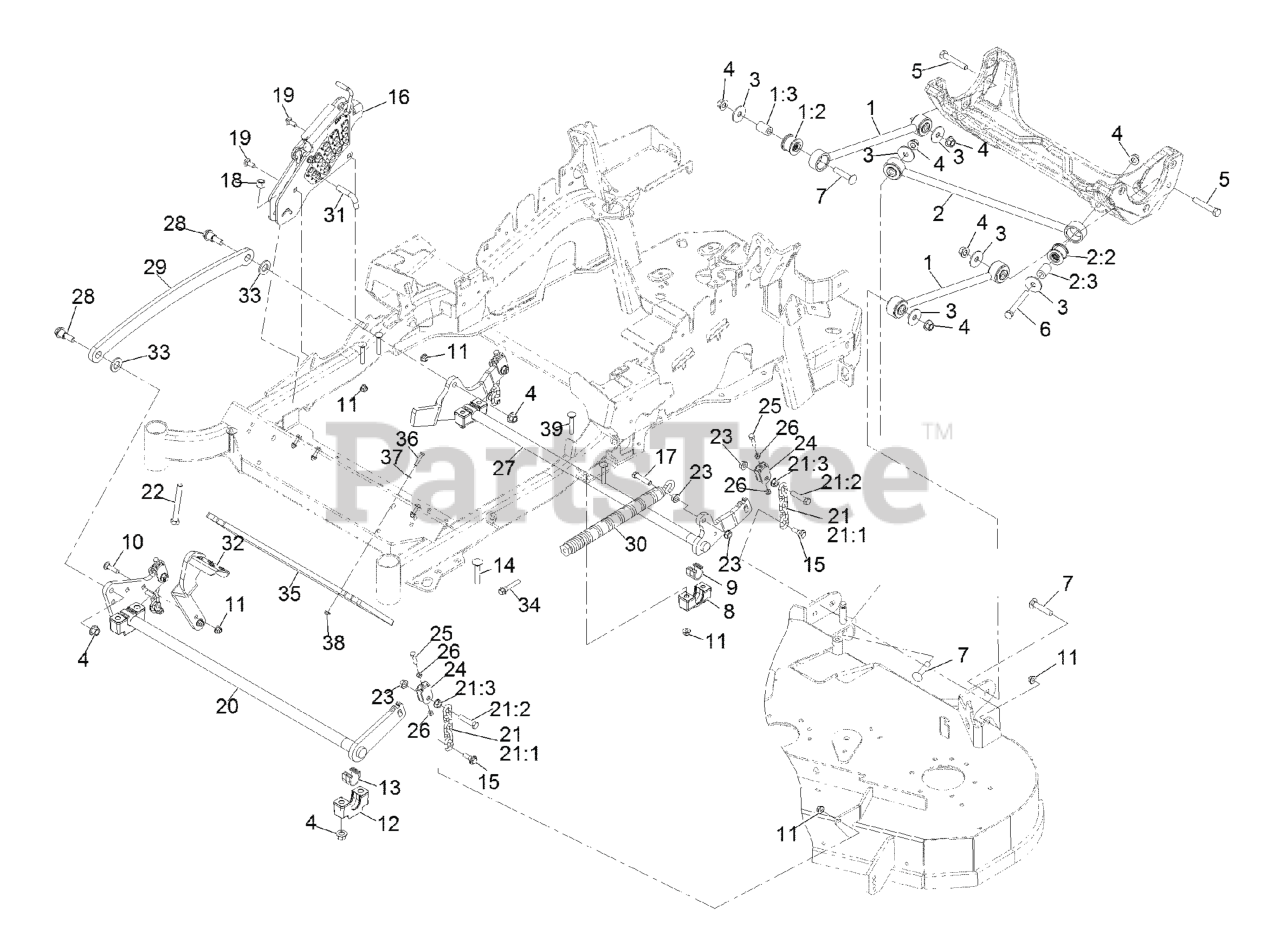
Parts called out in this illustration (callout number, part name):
1	DECK STRUT ASM
1:2	BUSHING-SUSPENSION, RUBBER
2	PANHARD ROD ASM
2:2	BUSHING-SUSPENSION, RUBBER
3	WASHER-THRUST
4	Nut-Lock 1/2-13
5	SCREW-HH
6	SCREW-HH
7	SCREW-CARR
8	SUPPORT-CROSS SHAFT, BEARING REAR
9	BEARING-CROSS SHAFT, REAR
10	SCREW-CARR
11	NUT-HF, NI
12	SUPPORT-CROSS SHAFT, BEARING
13	BEARING-CROSS SHAFT, FRON
14	Bolt-Carriage 1/2-13 X 2 1/2 Spl Neck
15	SCREW-SHOULDER, HHF
16	HOC ASM
17	SCREW-HH
18	NUT-LOCK, NI
19	BOLT-CARR
20	DECKLIFT-FRONT
21	DECK LIFT CHAIN ASM
21:1	CHAIN-LIFT, DECK
21:2	SCREW-HH
22	BOLT-TAP
24	YOKE-ADJUST, DECK
25	SCREW-HH
26	NUT-JAM
27	LIFT-DECK, REAR
28	SCREW-SHOULDER, HHF 1/2-13 X 1.12
29	LINK-LIFT, DECK
30	SPRING-EXTENSION
31	PIN-HOC
32	LEVER-FOOT
33	WASHER-FLAT
34	BOLT-SHOULDER
35	WEIGHT-TOE BOARD
36	SCREW-HH
37	WASHER-FLAT
39	Bolt-Carriage 3/8-16 X 2 1/4
